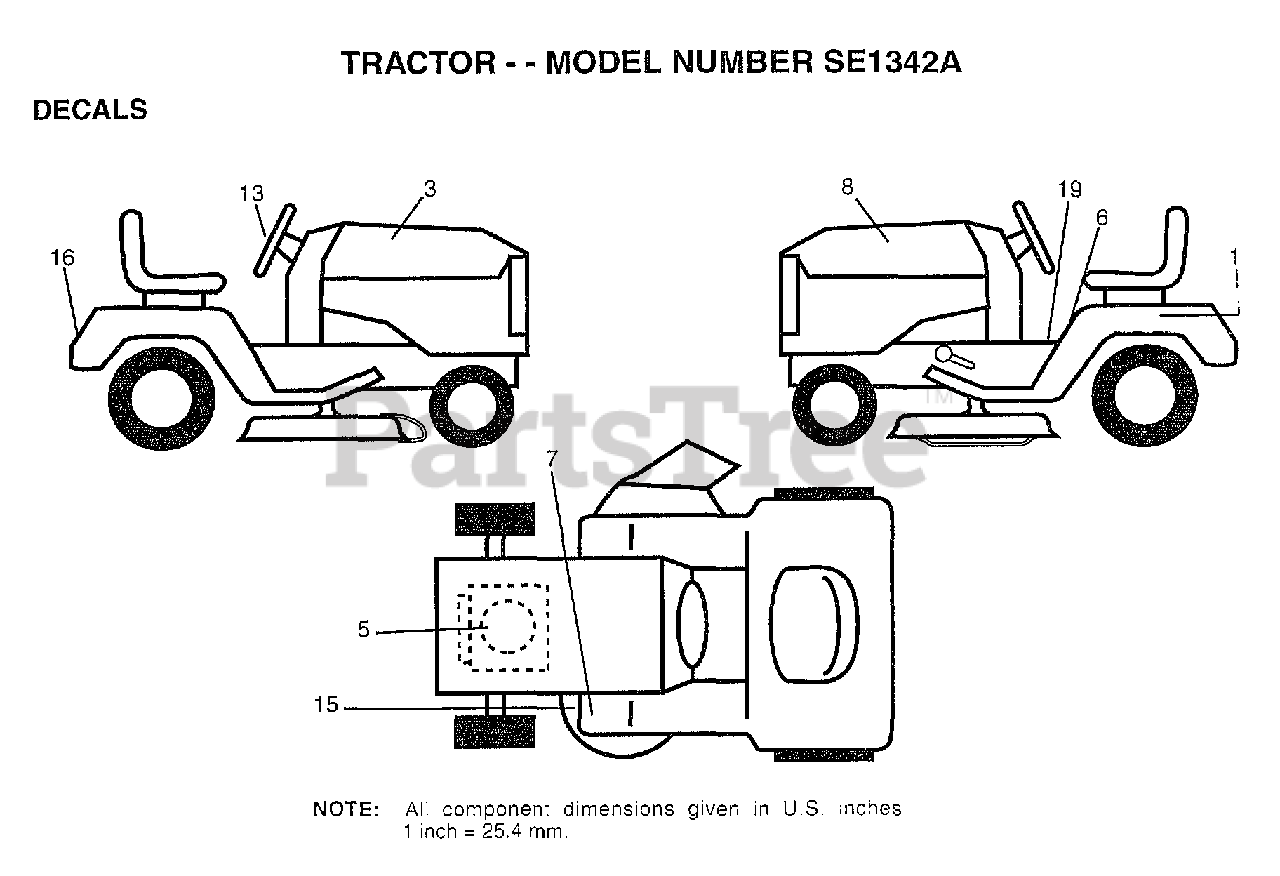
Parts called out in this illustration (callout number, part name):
1	DECAL.BATRY.3-3908
2	DECAL HOOD RH
3	DECAL ENGINE
6	"DECAL DANGER,FEND"
8	"DECAL.HOOD,LH"
13	"DECAL.INS,STRG WH"
15	DECAL
16	DECAL FENDER LOGO
19	"DECAL DASH,OPER."
